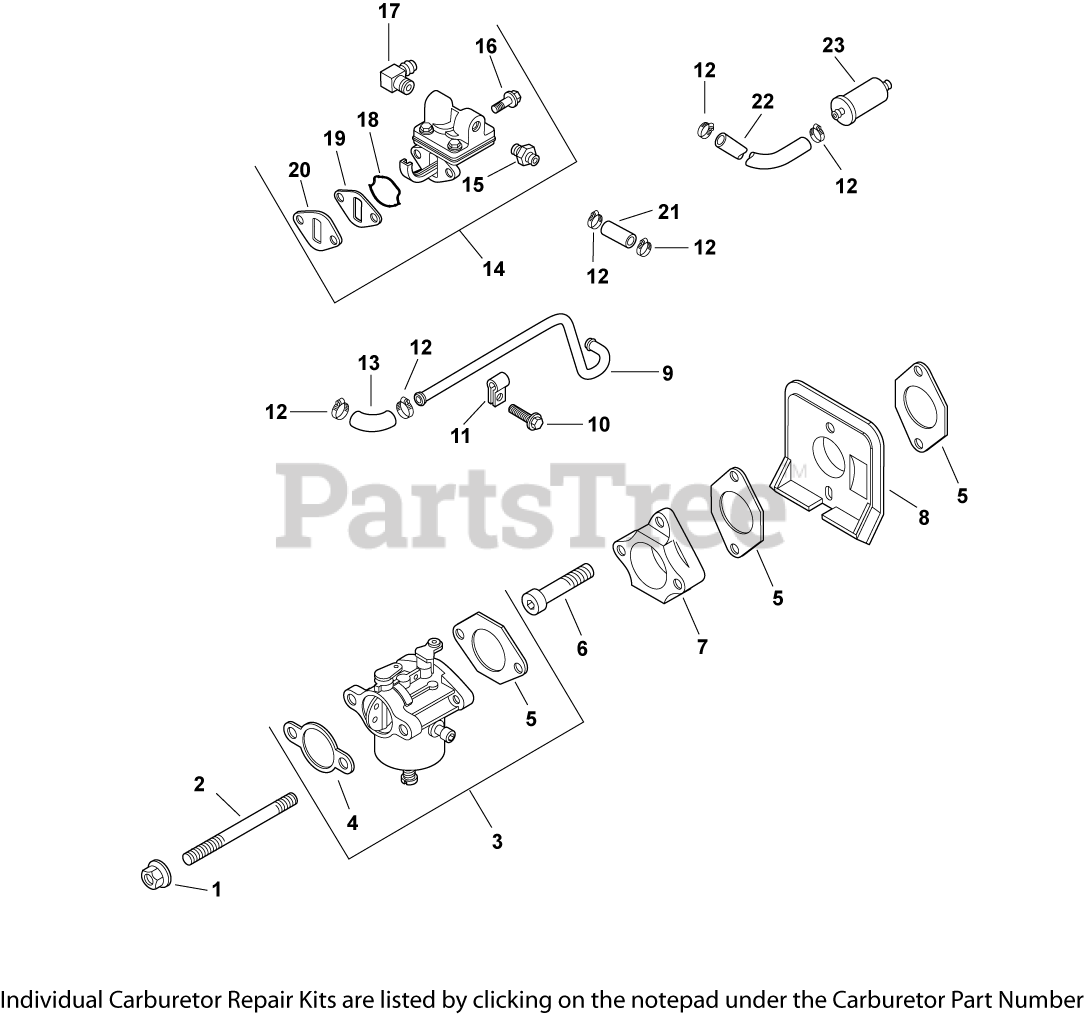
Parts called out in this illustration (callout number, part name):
1	NUT, FLG M6X1.0
2	STUD,M6X1.0X116
3	KIT, CARBURETOR
4	GASKET, AIR CLEANER BASE
5	GASKET, CARBURETOR
6	SCREW, SKT CAP M6X1.0X35
7	ADAPTER, CARBURETOR
8	DEFLECTOR, HEAT
9	LINE, FUEL - DISCONTINUED
10	SCREW, FLG THD FRM M5X.8X10
11	CLIP, TUBE & WIRING (KM)
12	CLAMP, HOSE (KM)-USE 25 237 31-S
13	HOSE, FUEL LOW-PERMEATION
14	KIT, FUEL PUMP
15	KIT, STRAIGHT FITTING
16	SCREW,FLG THD FRM M6X1.0X20-(#25086396S)
17	CONNECTOR, 90 DEG. HOSE
18	O-RING, FUEL PUMP
19	SPACER, FUEL PUMP
20	GASKET, FUEL PUMP
21	LINE - DISCONTINUED
22	LINE, FLEXIBLE FUEL - DISCONTINUED
23	FILTER, FUEL
